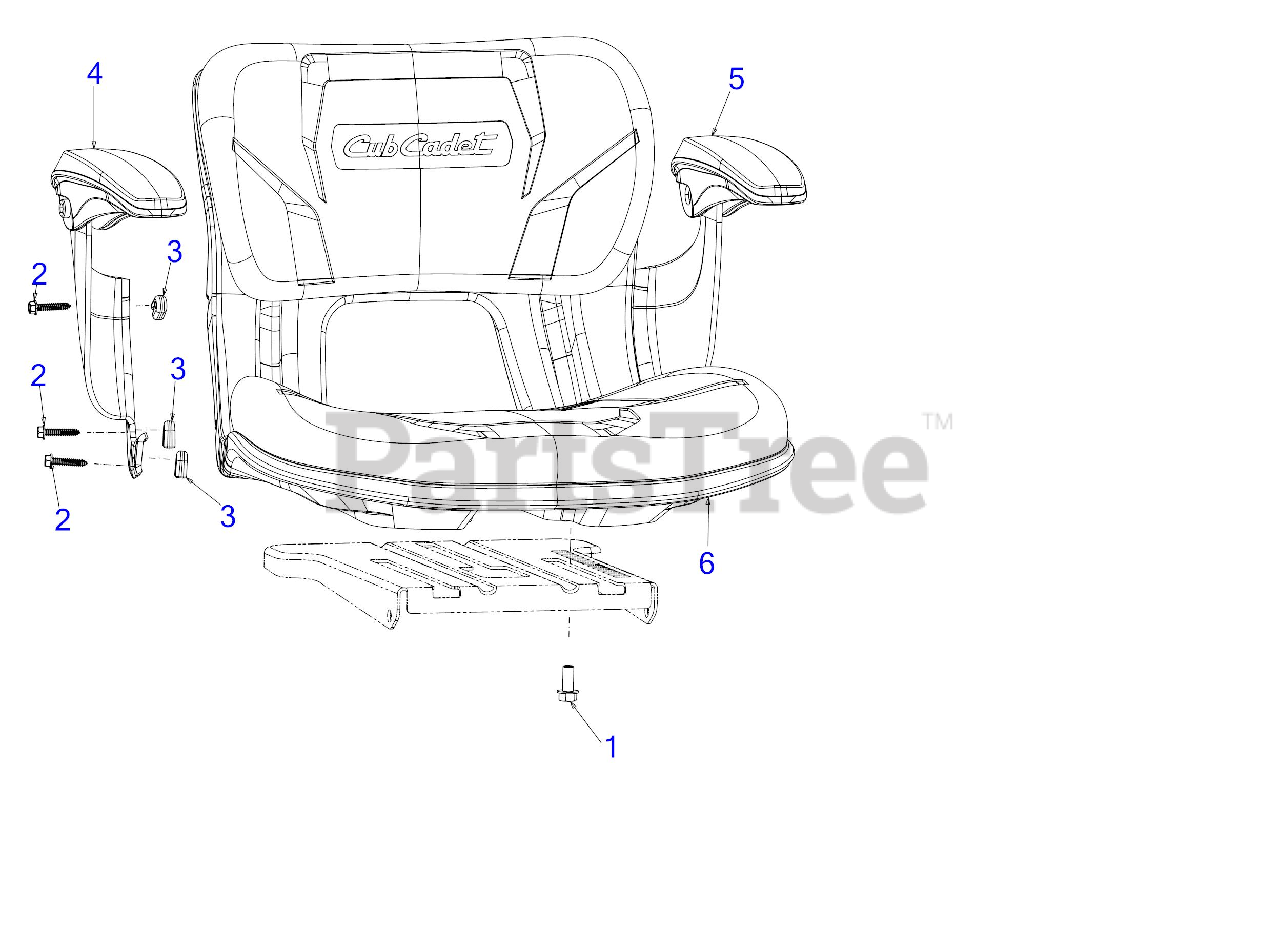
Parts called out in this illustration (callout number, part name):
1	SCREW 3/8-16 x .875 GR5
2	SCREW 1/4-14X 1.25
3	ARMREST NUT
4	ARM REST KIT
5	ARM REST KIT
6	SEAT (CUB WHITE LOGO FLAT)
